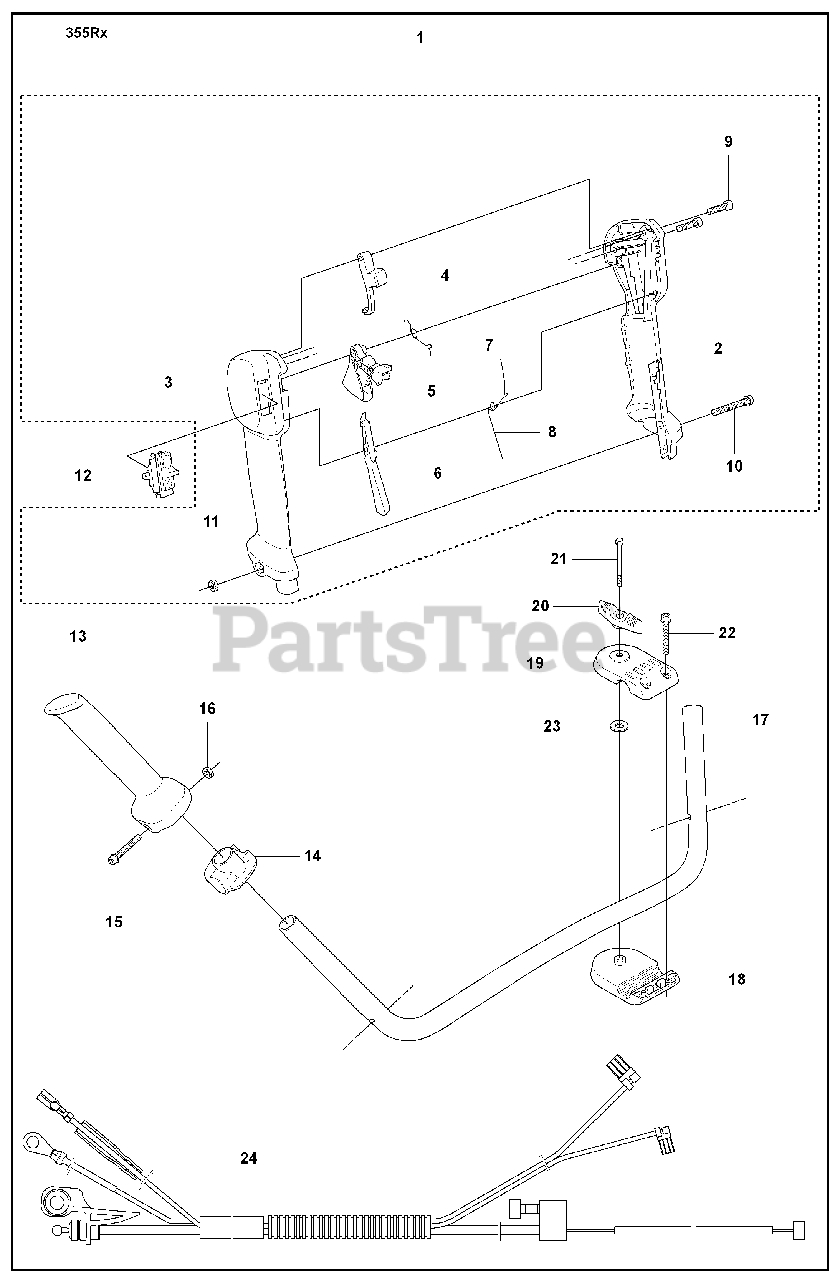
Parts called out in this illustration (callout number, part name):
2	HANDLE HALF RIGHT
3	HANDLE HALF LEFT
4	LOCKOUT STARTER THROTTLE
5	%THROTTLE TRIGGER
6	%THROTTLE LOCK
10	%SCREW
12	STOP BUTTON
16	NUT M6M M5
17	HANDLE
18	HANDLE HOLDER LOWER
19	HANDLE HOLDER UPPER
21	%SCREW
